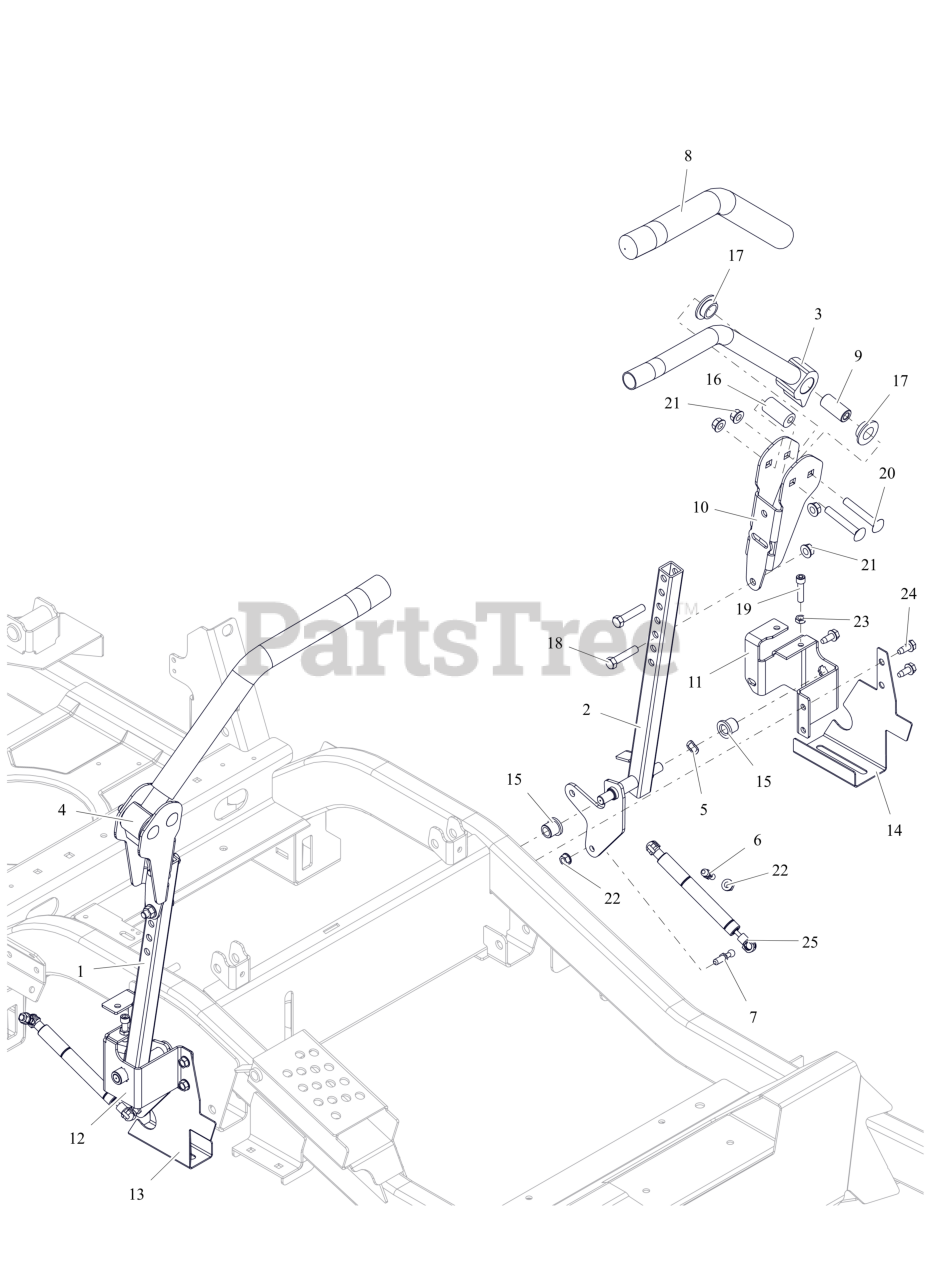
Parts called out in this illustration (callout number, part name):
1	WLDMT, STEERING RH
2	WLDMT, STEERING LH
3	WLDMT, CONTROL HANDLE-LH (BLACK)
4	WLDMT, CONTROL HANDLE-RH (BLACK)
5	WAVE WASHER .531X.781X.125FH
6	STUD- BALL
7	STUD-BALL-THREADED
8	GRIP, HANDLEBAR
9	SPACER, STEERING ARM
10	ADJ UPPER CONTROL ARM BRKT-BLK
11	BRKT, STEERING ARM MOUNT -LH
12	BRKT, STEERING ARM MOUNT -RH
13	GUARD, FRAME RAIL BELT RH
14	GUARD, FRAME RAIL BELT LH
15	BHSG-FLG .500X.750X.750X.125
16	BSHG, ECCENTRIC.406X.875X1.625
17	BSHG-FLG .762X1.48X.44 NYL
18	BLT, HEX .38-16X1.75 G5 ZCC
19	BLT, SHCS .312-18X1.25 G8 SS
20	BLT, RHSSN.38-16X2.50 G5 ZCC
21	NUT-LK-TOP-FLG .38-16 ZC120
22	NUT,LK-CTR-FLG .31-18 GF ZCC
23	NUT-JAM .312-18 G2 ZCC
24	SCR,TAP .312-18X.75 HWH TR ZCC
